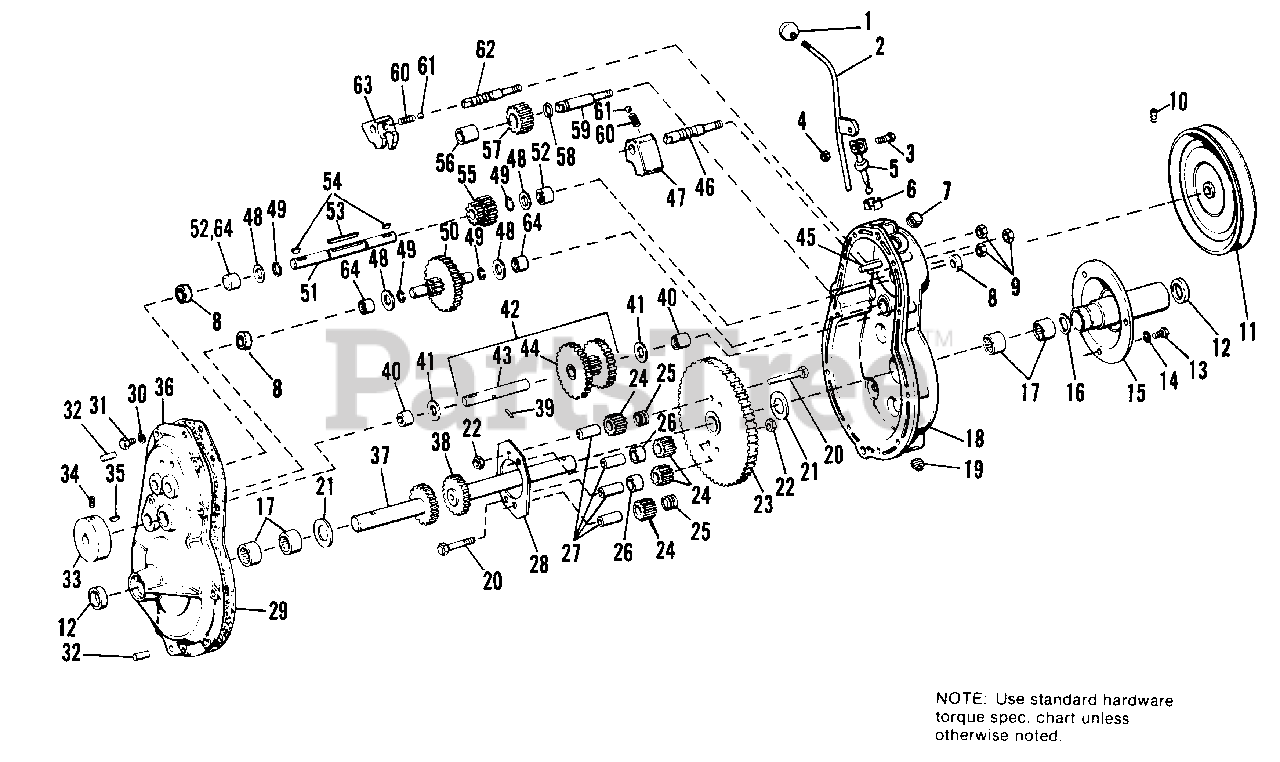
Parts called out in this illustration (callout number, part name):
2	ROD ASSY., Shift
3	CAPSCREW, Hex Hd., 1/4-20 x 3/4
4	LOCKNUT, Hex, 1/4-20
5	ROD ASSY., Shift
6	BUSHING, Half
9	NUT, Hex, Full, 7/16-14
10	SETSCREW, 3/8-24 x 3/8
13	CAPSCREW, Hex Hd., 3/8-16 x 7/8
14	LOCKWASHER, 3/8
15	HOUSING ASSY., Axle
17	BEARING, Roller
18	CASE ASSY., Gear
19	PLUG, Pipe, 3/8
20	CAPSCREW, Hex Hd., 3/8-16 x 2-1/2
22	LOCKNUT, Hex, 3/8-16
23	GEAR ASSY., Drive
24	PINION, Diff.
26	SPACER, Diff.
27	SPINDLE, Diff.
28	PLATE, Diff.
30	LOCKWASHER, 5/16
31	CAPSCREW, Hex Hd., 5/16-18 x 1-1/4
32	PIN, Roll, 3/8 x 1
33	DRUM, Brake
34	SETSCREW, 5/16-18 x 1/2
36	COVER ASSY., Gear Case
37	SHAFT ASSY., Axle, L.H.
38	SHAFT ASSY., Axle, R.H.
39	PIN, Dowel
40	BEARING, Roller (Qty. 2 on 990486 & 990542 Only)
42	SHAFT & GEAR ASSY.
43	SHAFT & BRAKE
44	GEAR ASSY., Cluster
45	PIN ASSY., Roll
46	SHAFT, Shift, Hi-Lo
47	FORK, Shift, I & II
49	RING, Retaining
50	GEAR & SHAFT ASSY.
51	SHAFT, Pulley, P.T.O. (990597 & 990598 Only)
51	SHAFT, Pulley, P.T.O.
52	BEARING, Roller (Qty. 1 on 990486 & 990542 Only)
53	KEY (990597 & 990598 Only)
55	PINION ASSY., Hi-Lo
56	BEARING, Roller
57	PINION, Reverse
59	SHAFT, Pinion, Reverse
60	SPRING (990597 & 990598 Only)
61	BALL, Shift Lock
62	SHAFT, Shift, Reverse
63	FORK, Shift, Reverse
64	BEARING, Roller (990486 & 990542 Only)
